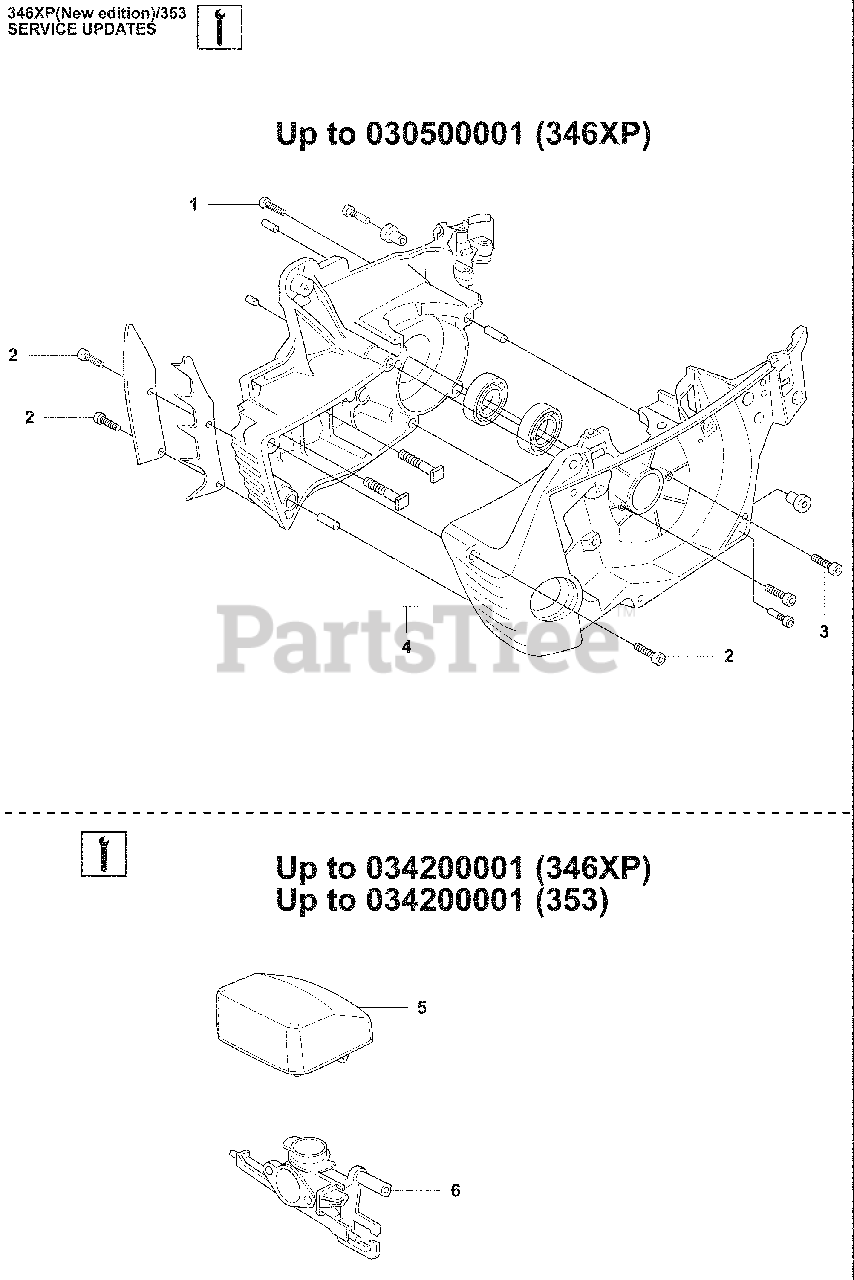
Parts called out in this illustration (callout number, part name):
1	Screw
2	Screw
3	Screw
5	Air Filter, Nylon B
5	Air Filter, Nylon Y
5	Air Filter, Felt
